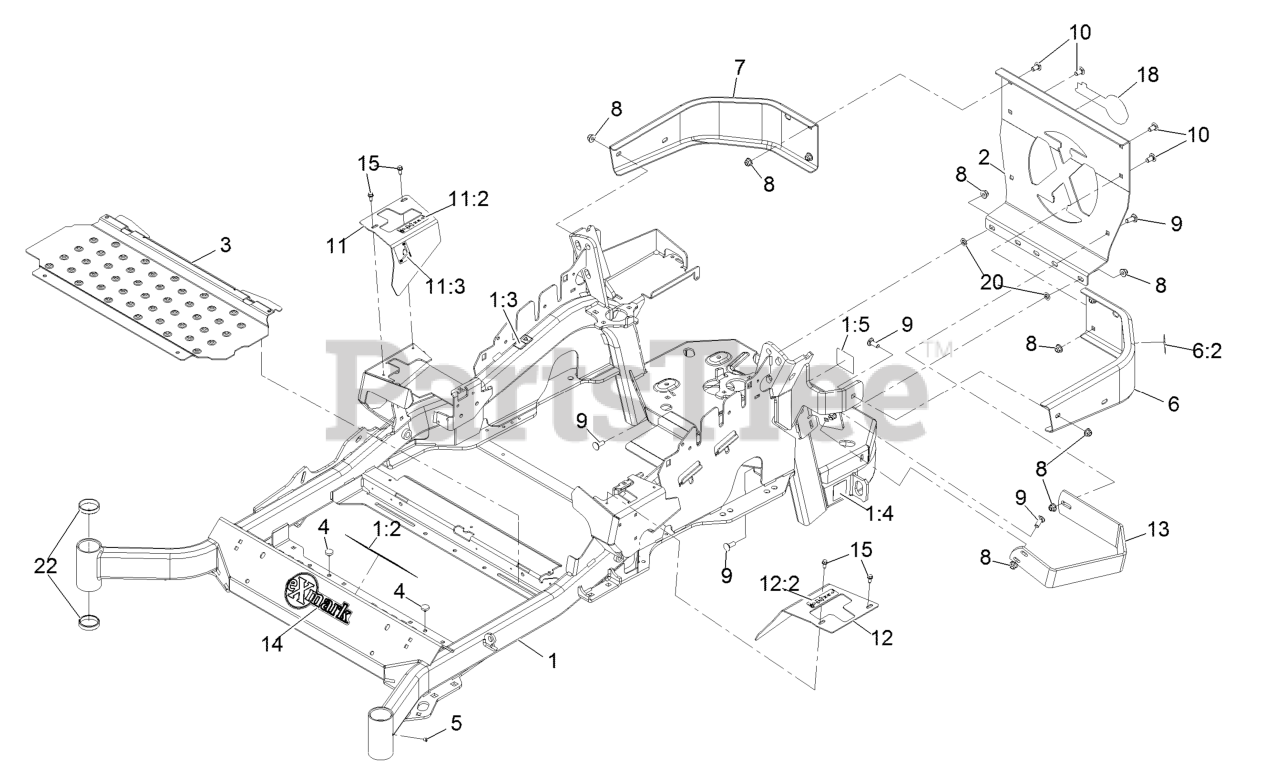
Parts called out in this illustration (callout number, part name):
1	Mainframe ASM
1:2	Decal-Danger
1:3	Decal-Warning
1:4	Decal-Hazard, Pinched Finger
1:5	Decal-Spark Arrester
2	Plate,Rear Guard
6	LH Bumper ASM
6:2	Decal-Warning
7	Bumper-RH
8	Nut-Nyloc 3/8-16 Flg
9	Bolt-Carriage 3/8-16 X 1
10	Bolt-Carriage 3/8-16 X 3/4
11	RH Motion Control Cover ASM
11:2	Decal-Control, Motion
11:3	Decal-Park Brake, CE
12	LH Motion Control Cover ASM
12:2	Decal-Control, Motion
13	Guard-Muffler
14	Decal-Exmark
15	Screw-HWH 1/4-20 X .62
18	Decal-Exmark Logo
20	Nut-Push 3/8-16
22	Cup-Bearing Tapered Roller
